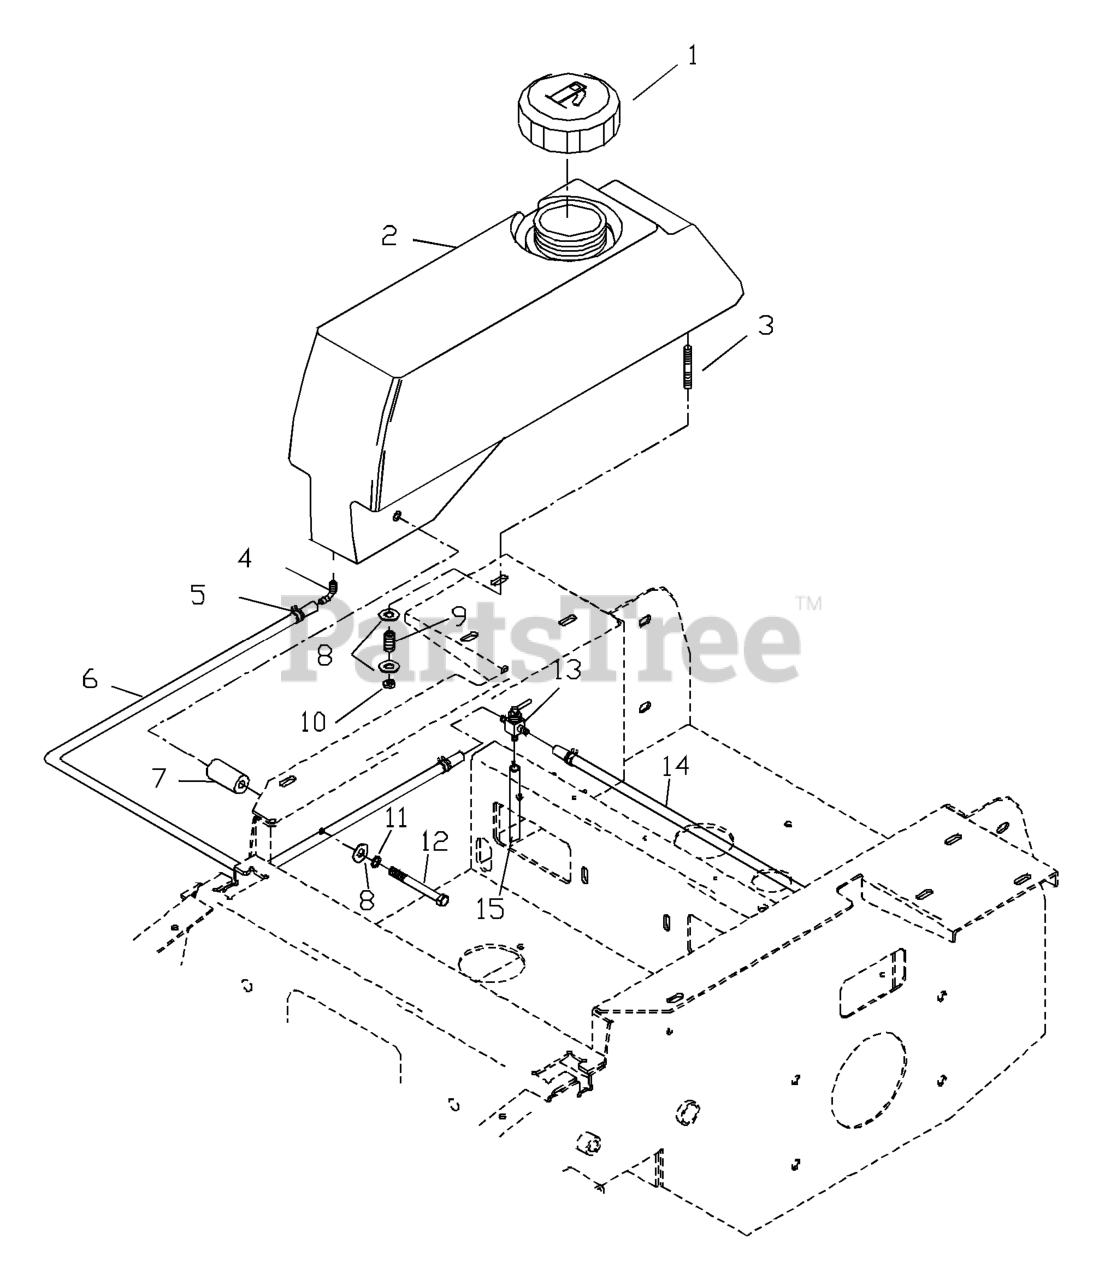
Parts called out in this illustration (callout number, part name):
1	FUEL CAP
2	FUEL TANK RT
2	LEFT TANK W/CUP HOLDER
3	STUD, 5/16C
4	HOSE BARB 90 DEGREE
5	HOSE CLAMP
6	FUEL LINE 29.5"
7	TANK SPACER
8	WASHER 5/16 FLAT
10	NUT 5/16C CENTERLOCK
11	WASHER.LOCK.HVY.HLCL.SPR.5/16
12	HCS 5/16C X 4
13	FUEL VALVE
15	FUEL LINE 16"
